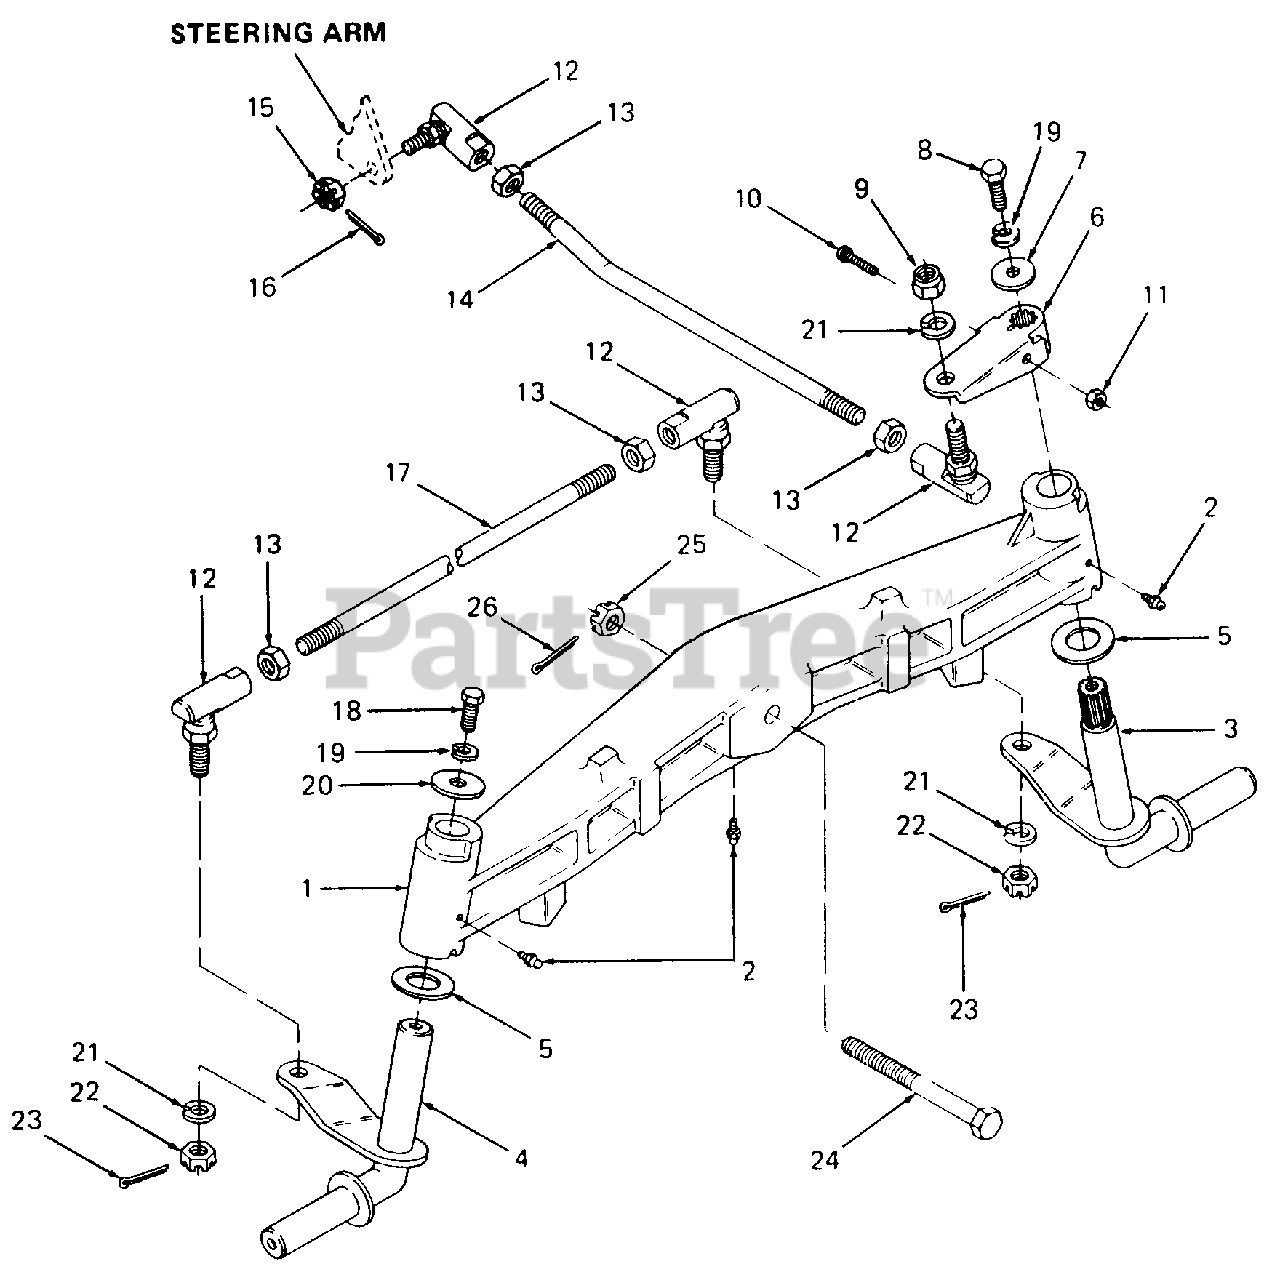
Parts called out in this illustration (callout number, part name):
3	Knuckle, Steering - LH
4	Knuckle, Steering - RH
5	Washer, Thrust, 1.03 X 1.62 X .03 Thk HDN
6	Arm, Steering
7	Washer, Flat, .406 X 1.25 X .157 Thk
8	Screw, Hex Cap, 3/8-24 X 1.0 Lg
9	Nut, Hex Top Lock, 1/2-20
10	Screw, Socket Hd Cap, 1/4-20 X 1.38 Lg
11	Nut, Hex Patch Lock, 1/4-20
12	Ball Joint
13	Nut, Hex Jam, 1/2-20 GR5
14	Link, Drag
15	Nut, Hex Castle, 1/2-20 GR5
16	Pin, Cotter, 3/32 Dia X 1.25 Lg
18	Screw, Hex Cap, 3/8-24 X 1.0 Lg
19	Washer, Lock, 3/8
20	Washer, Flat, .406 X 1.5 X .12 Thk
21	Washer, Lock, 1/2
22	Nut, Hex Castle, 1/2-20 GR5
23	Pin, Cotter, 3/32 Dia X 1.25 Lg
24	Bolt, Hex, 3/4-10 X 5.25 Lg GR5
25	Nut, Hex Castle, 3/4-10
26	Pin, Cotter, 1/8 Dia X 1.5 Lg
